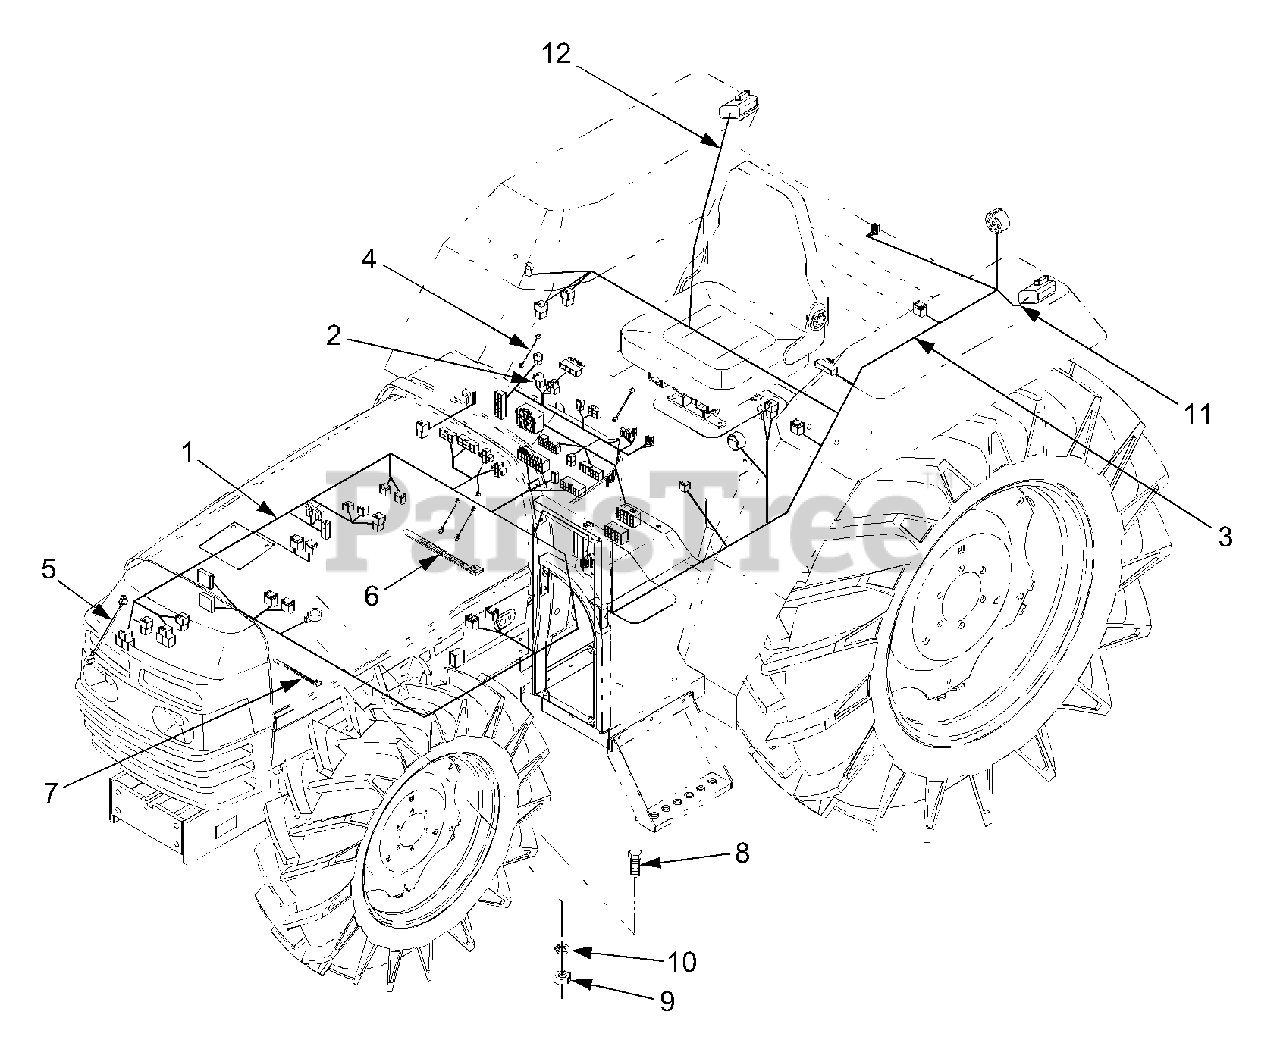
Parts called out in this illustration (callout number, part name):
1	Wire Harness Ass'y
2	Wire Harness Ass'y
3	Wire Harness Ass'y
4	Wire, Harness 2
5	Wire, Harness 3
10	Washer, Spring
11	Wire Connection (LH)
12	Wire Connection (RH)
